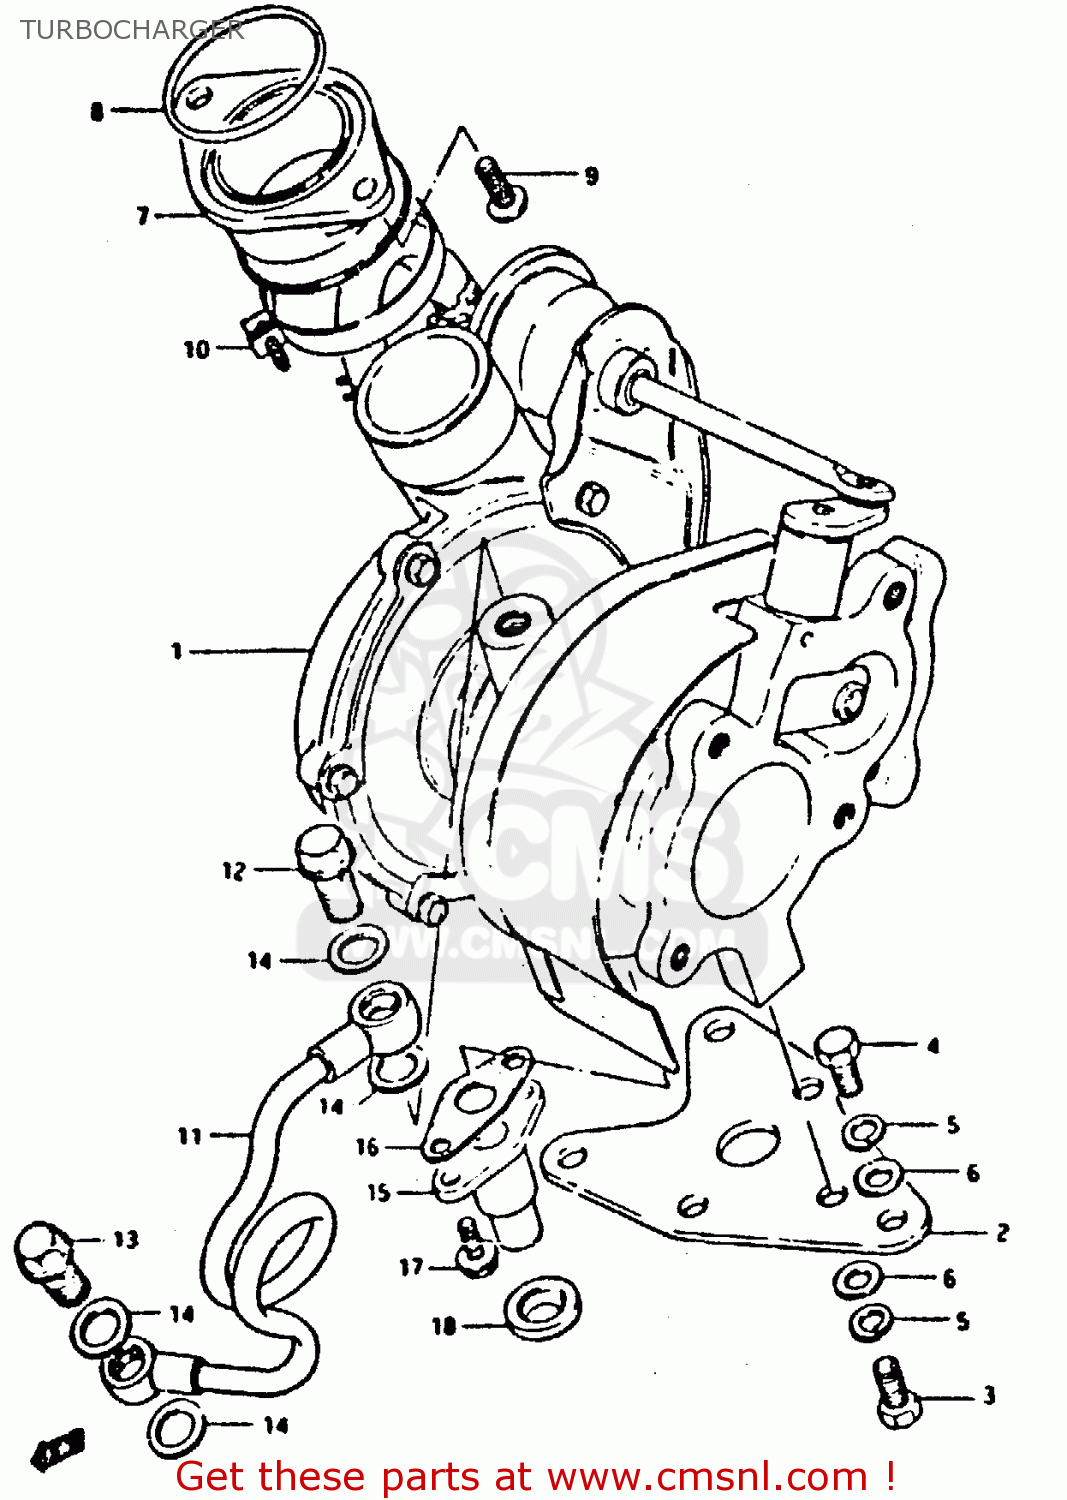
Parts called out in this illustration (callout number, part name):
1	CHARGER ASSEMBLY,TURBO
2	CHARGER ASSEMBLY,TURBO
3	BOLT
4	BOLT
5	LOCK WASHER
6	WASHER
7	COVER
8	O-RING
9	SCREW
10	CLAMP
11	TANK COMP,OIL CATCH
12	BOLT UNION
13	BOLT UNION
14	GASKET(10X15X1)
15	CONNECTOR, OIL OUTLET
16	GASKET (MCA)
17	BOLT
18	OIL SEAL
